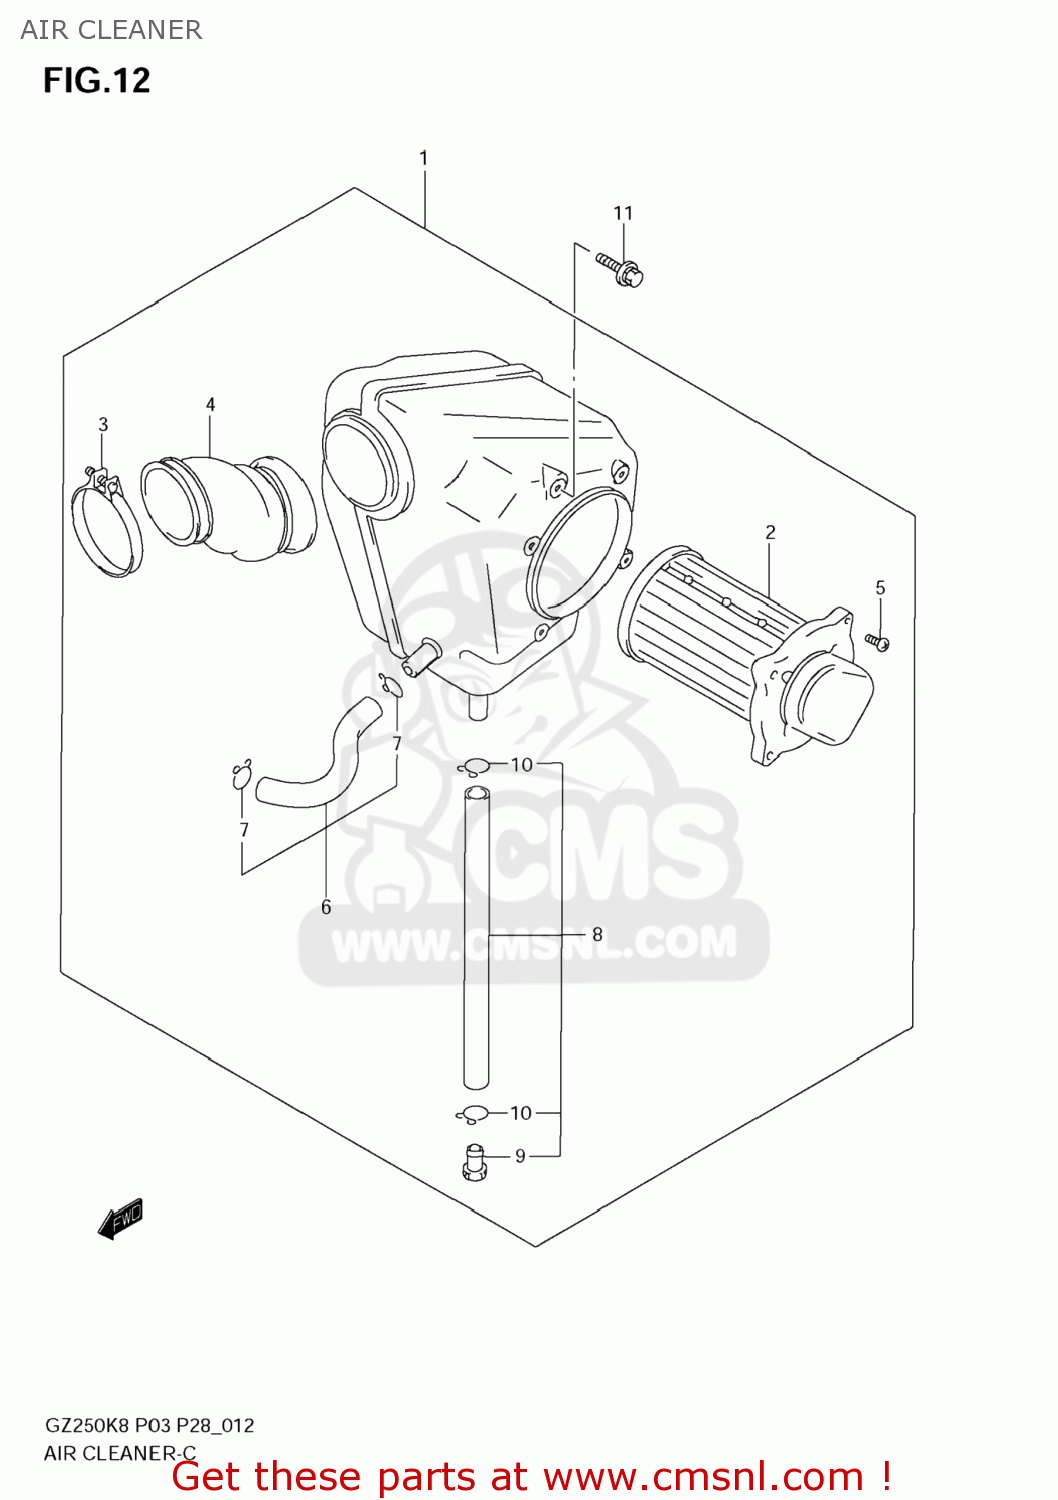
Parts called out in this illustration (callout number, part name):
1	CLEANER ASSY,AIR
2	FILTER,AIR CLEANER
3	CLAMP
4	TUBE,OUTLET
5	SCREW
6	TUBE,BREATHER
7	CLIP
8	TUBE,DRAIN
9	PLUG
10	CLIP
11	BOLT
